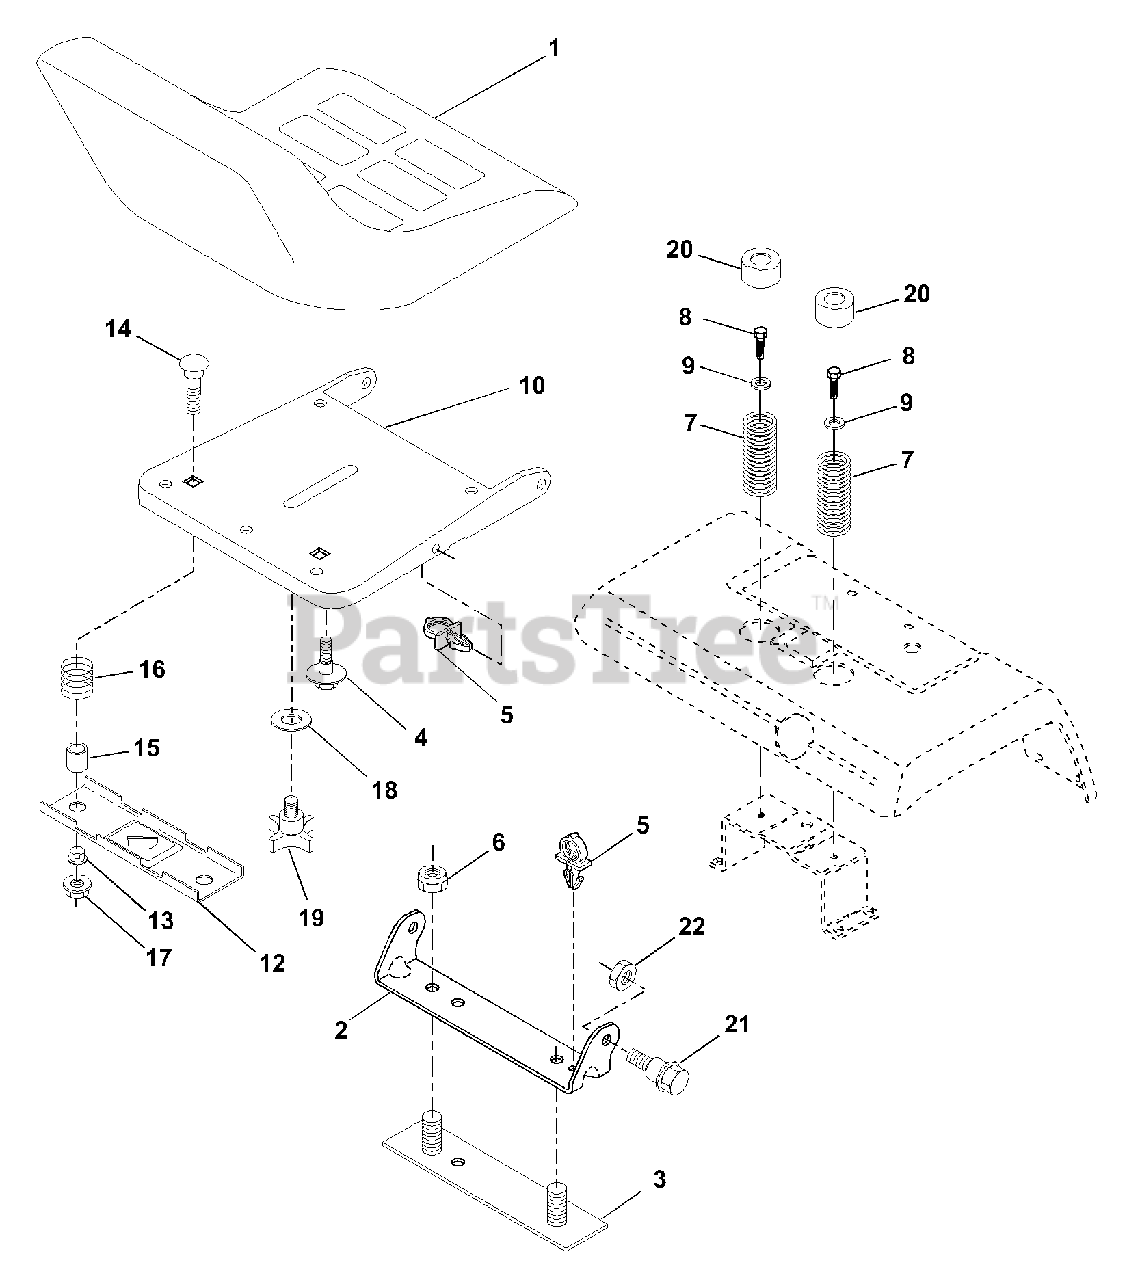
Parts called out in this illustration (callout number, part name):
1	Seat
2	Bracket, Pivot Seat
3	Strap, Fender
4	Bolt, Shoulder 5/16-18 X .62
5	Clip, Push In
6	Nut, Crownlock 3/8-16 Unc
7	Spring, Seat Cprsn
8	Screw, Thdrol 5/16-18 X 1/2
9	Washer 13/32 X 1 X 14 Ga.
10	Pan, Seat
12	Bracket, Mounting Switch
13	Bushing, Snap
14	Bolt, Carriage 1/4-20 X 1-3/8
15	Spacer, Split
16	Spring, Cprsn
17	Nut, Lock 1/4 Lge Flg Gr. 5
18	Washer 17/32 X 1-3/16 X 12 Ga.
19	Knob, Seat 1/2-13 Unc
20	Cap, Spring Seat
21	Bolt, Shoulder 5/16-18 Unc
22	Nut, Crownlock 5/16-18 Unc
